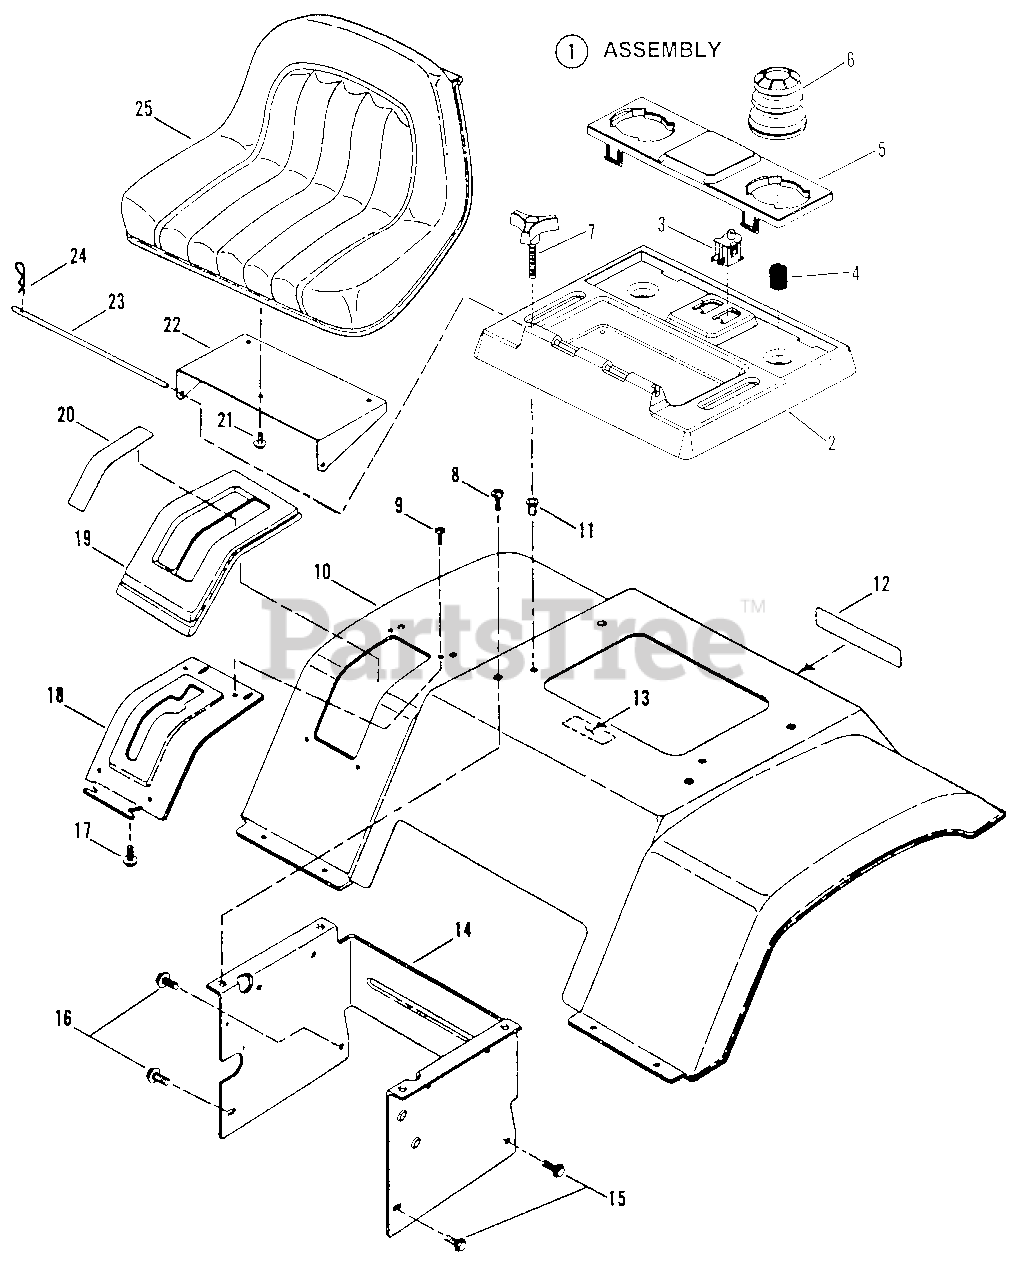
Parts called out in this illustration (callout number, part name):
1	ASSEMBLY, Seat Support
2	SUPPORT, Seat
3	SWITCH, Seat, Gray, NC
4	SPRING
5	HOLDER, Cushion
6	CUSHION, Seat
7	KNOB, Seat Adjustment
8	SCREW, 5/16-18 x 5/8" Truss Head, Torx
9	SCREW, 1/4-20 x 5/8" Hex Washer Head, Self-Tapping
10	PAN, Seat (Fender)
11	RIV-NUT, 5/16-18 Round
12	DECAL - SNAPPER, 7.28" Molded Logo, White Letters & Stripe
12	DECAL - SNAPPER, 7.28" Molded Logo, Silver Letters & Blue Stripe
13	DECAL - CAUTION, Battery Location
14	SUPPORT, Fender, Electric Clutch
15	SCREW, 5/16-18 x 5/8" Hex Washer Head, Swage Form
16	SCREW, 5/16-18 x 1-1/4" Hex Washer Head, Swage Form
17	SCREW, #10-16 x 1/2" Hex Washer Head, Self-Tapping
18	DETENT, Shift
19	COVER, Shift
20	DECAL, Shift Cover, 5-Speed
21	BOLT, 5/16-18 x 1/2" Hex Flange Lock, Grade 5
22	BRACKET, Seat Support
23	ROD, Seat Hinge
24	PIN, 3/32 x 1-1/2" Hair
25	SEAT, Operator's
25	SEAT, Operator's, High Back, 3-Hole
25	SEAT, Replacement for all above
